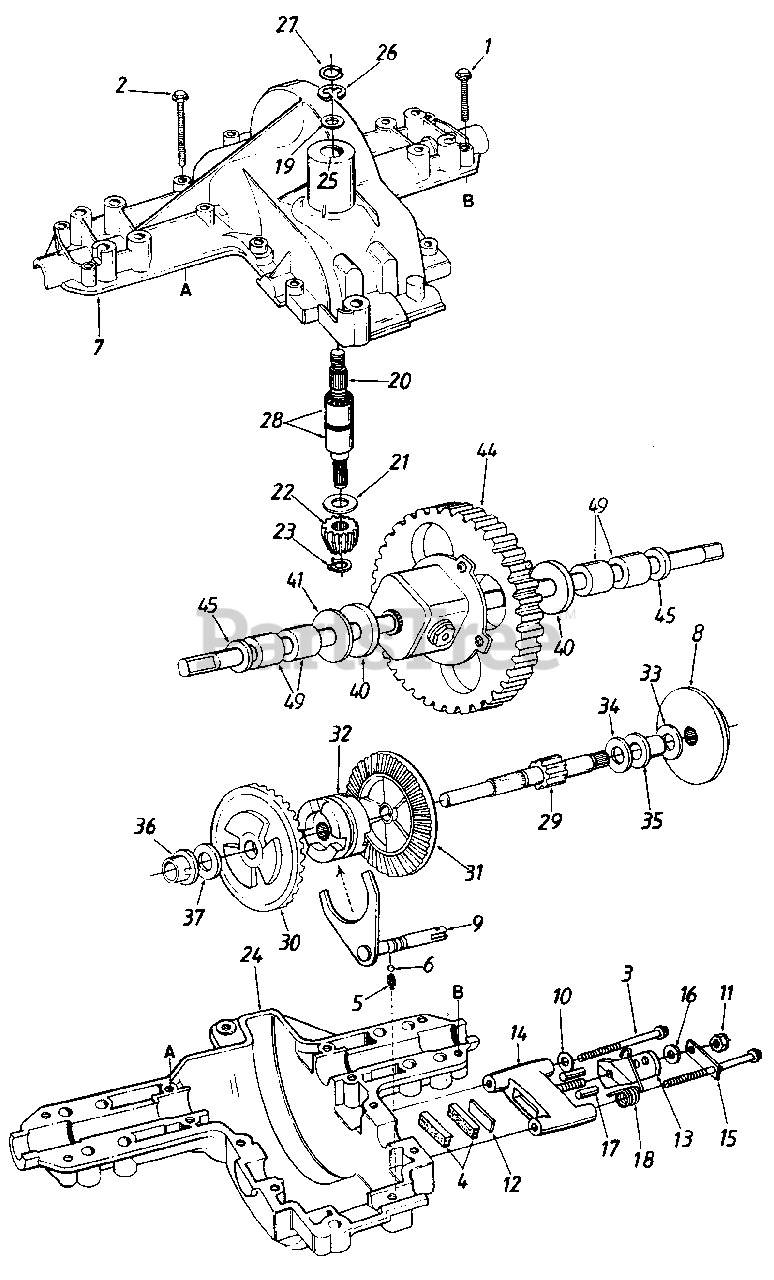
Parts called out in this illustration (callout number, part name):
1	Hex Wash. Hd. TT-Tap Scr. 1/4-20 x 1.25" Lg.
2	Hex Wash. Hd. TT-Tap Scr 1/4-20 x 1.75" Lg.
3	Hex Wash. Hd. Tap Scr. 1/4-20 x 2.38" Lg.
4	Brake Puck
5	Spring Detent
6	Ball Detent
7	Upper Housing
8	Brake Disc
9	Shift Fork Ass'y.
10	Fl-Wash. .312" I.D. x .75" O.D.
11	Hex Top L-Nut 5/16-24 Thd.
12	Puck Plate
13	Actuating Arm - L.H.
14	Brake Yoke
15	Anti Rotation Brkt.
16	Fl-Wash. 11/32" I.D. x 7/8" O.D.
17	Actuating Pin
18	Torsion Spring
19	Washer
20	Input Shaft
21	Fl-Wash. 5/8" I.D. x 1.25" O.D.
22	Pinion Input 14T
23	Retaining Ring
24	Lower Housing
25	Oil Seal
26	"E"-Ring
27	Wire Ring
28	Needle Bearing
29	Drive Shaft - L.H. Brake
30	Bevel Gear 42T Small I.D.
31	Bevel Gear 42T Large I.D.
32	Clutch Collar
33	Washer
34	Fl-Wash. .7" I.D. x 1.125" O.D.
35	Flanged Brg. 5/8" I.D. x 15/16" Lg.
36	Flanged Brg. 5/8" I.D. x 3/4" Lg.
37	Washer
40	Axle Spacer
41	Washer
44	Differential Ass'y.
45	Seal
49	Sleeve Brg. 3/4" I.D. x 1" Lg.
